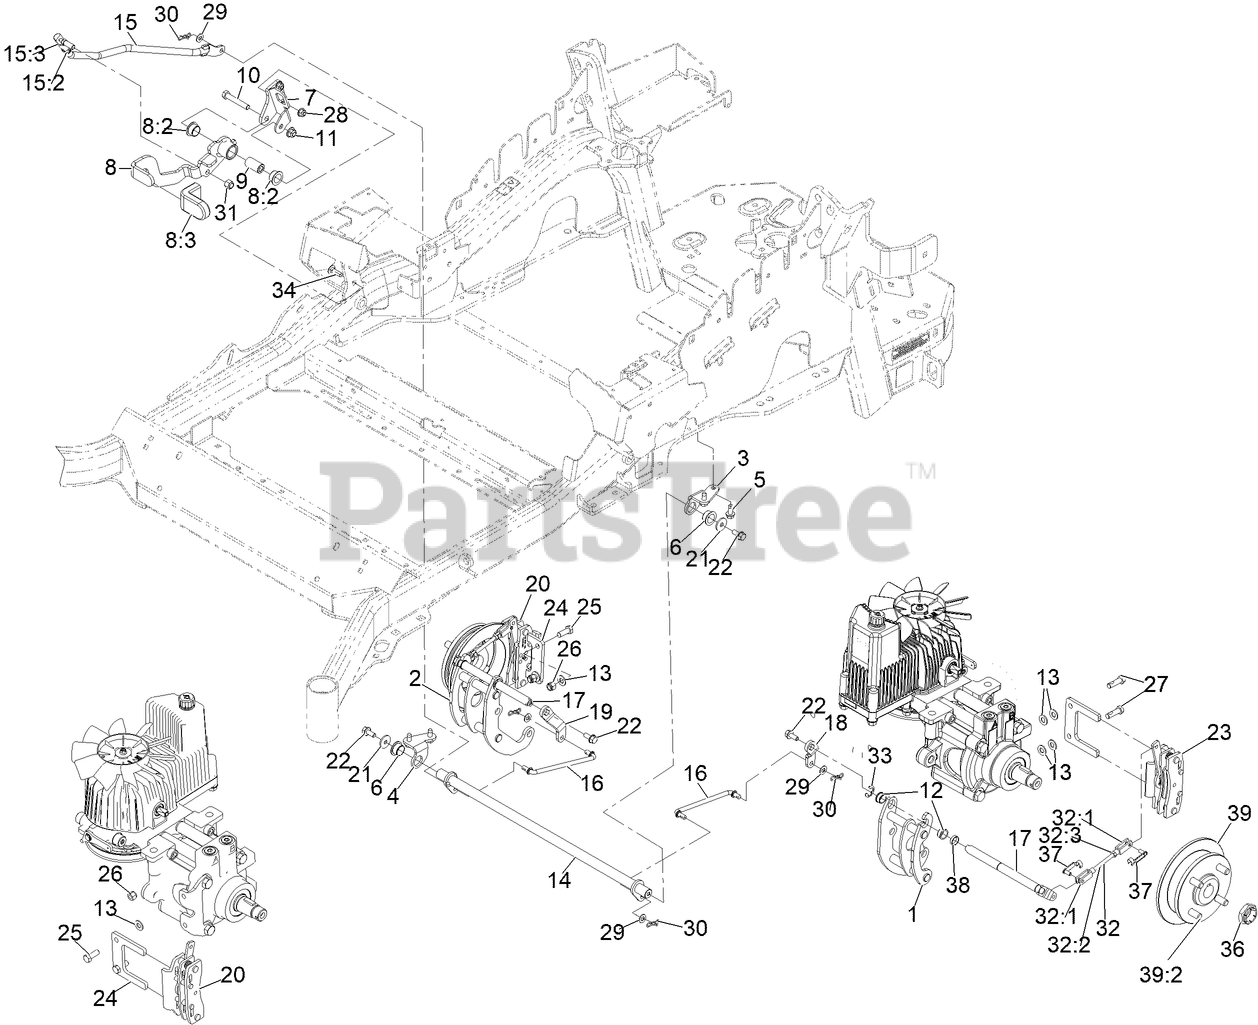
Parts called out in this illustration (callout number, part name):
1	MOUNT-BELLCRANK, LH
2	MOUNT-BELLCRANK, RH
3	MOUNT-PIVOT, LH
4	MOUNT-PIVOT, RH
5	SCREW-HWHTF
6	BUSHING-FLANGE
7	BRACKET-MOUNT
8	BRAKE LEVER ASM W/GRIP M-R
8:2	BUSHING-FLANGE
8:3	GRIP-LEVER
9	HANDLE-PIVOT, BRAKE
10	SCREW-HH
11	NUT-HF, NI
12	BUSHING
13	WASHER-FLAT
14	SHAFT-CROSS
15	ASM, FRONT LINKAGE
15:2	END-TIE ROD, RH
15:3	NUT-HJ
16	LINK-MID
17	BELLCRANK
18	ARM-INNER, LH
19	ARM-INNER, RH
20	CALIPER-BRAKE, RH
21	WASHER-FLAT
22	SCREW-HHF
23	CALIPER-BRAKE, LH
24	PLATE-MOUNT, BRAKE
25	SCREW-HH,
26	NUT-LOCK
27	SCREW-HH, PATCH,
28	NUT-HF, NI
29	WASHER-PLAIN
30	PIN-COTTER, LOCKING
31	NUT-LOCK
32	REAR LINKAGE ASM
32:2	LINKAGE, REAR
32:3	NUT-JAM
33	E-RING
34	BOLT-CARR
36	LOCKNUT
37	PIN-CLEVIS, SPRING
38	SPACER
39	WHEEL HUB ASM
39:2	STUD-WHEEL
